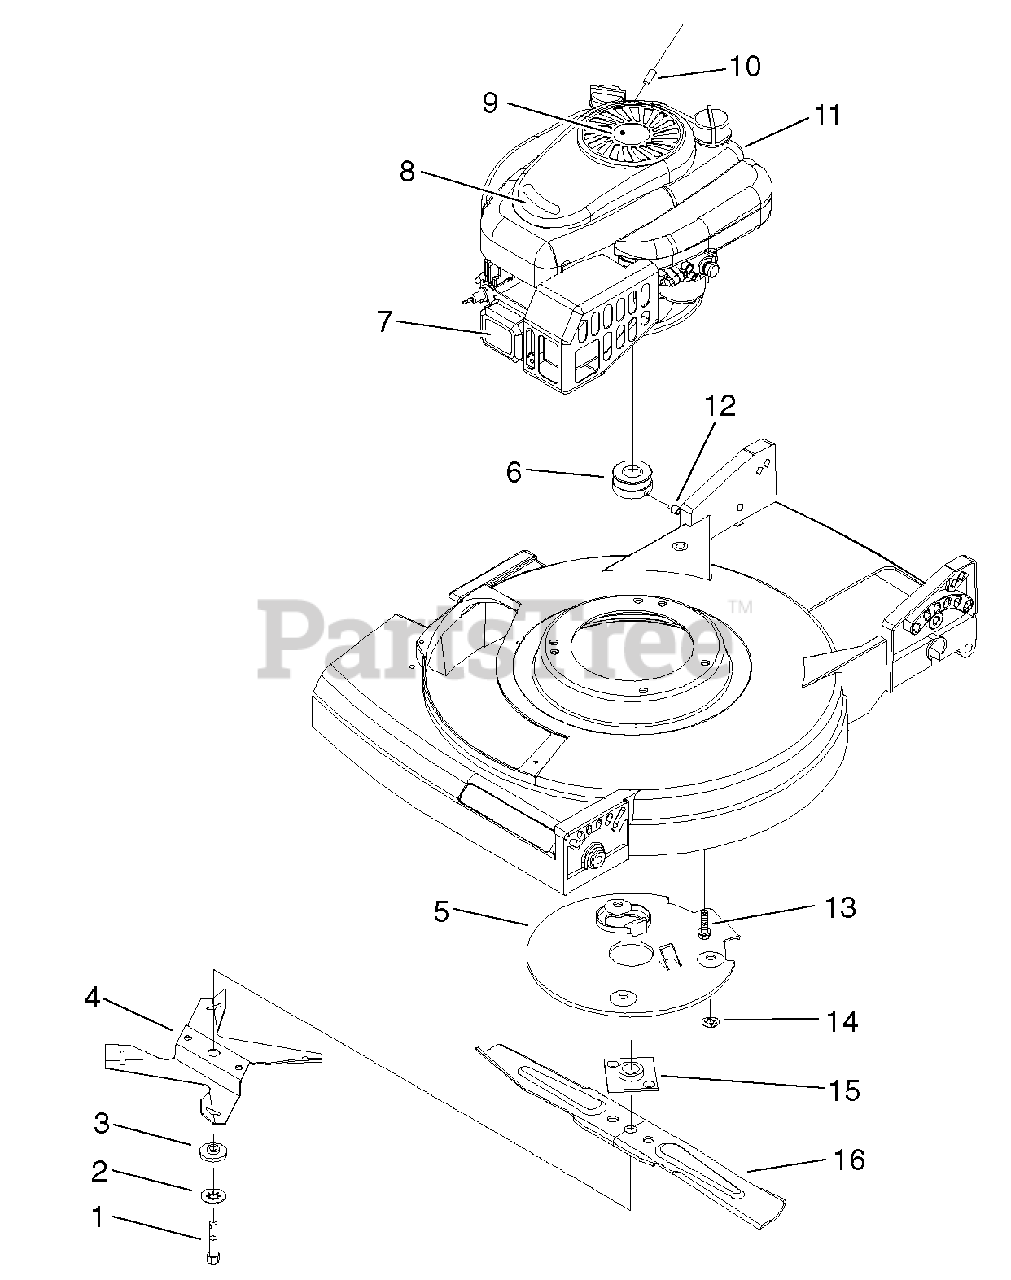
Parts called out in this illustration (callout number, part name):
1	Bolt-Blade
2	Washer-Lock
3	Spacer-Blade
4	Fan-Mulching
5	Shield-Grass
7	Decal-Surface, Hot
8	Applique
9	Decal-Recoil
10	Stop-Rope
11	Engine-Tecumseh OVRM105-21038F
12	Screw-Set, Cone Point
13	Screw-Taptite
14	Push Nut
15	Plate & Collar ASM
